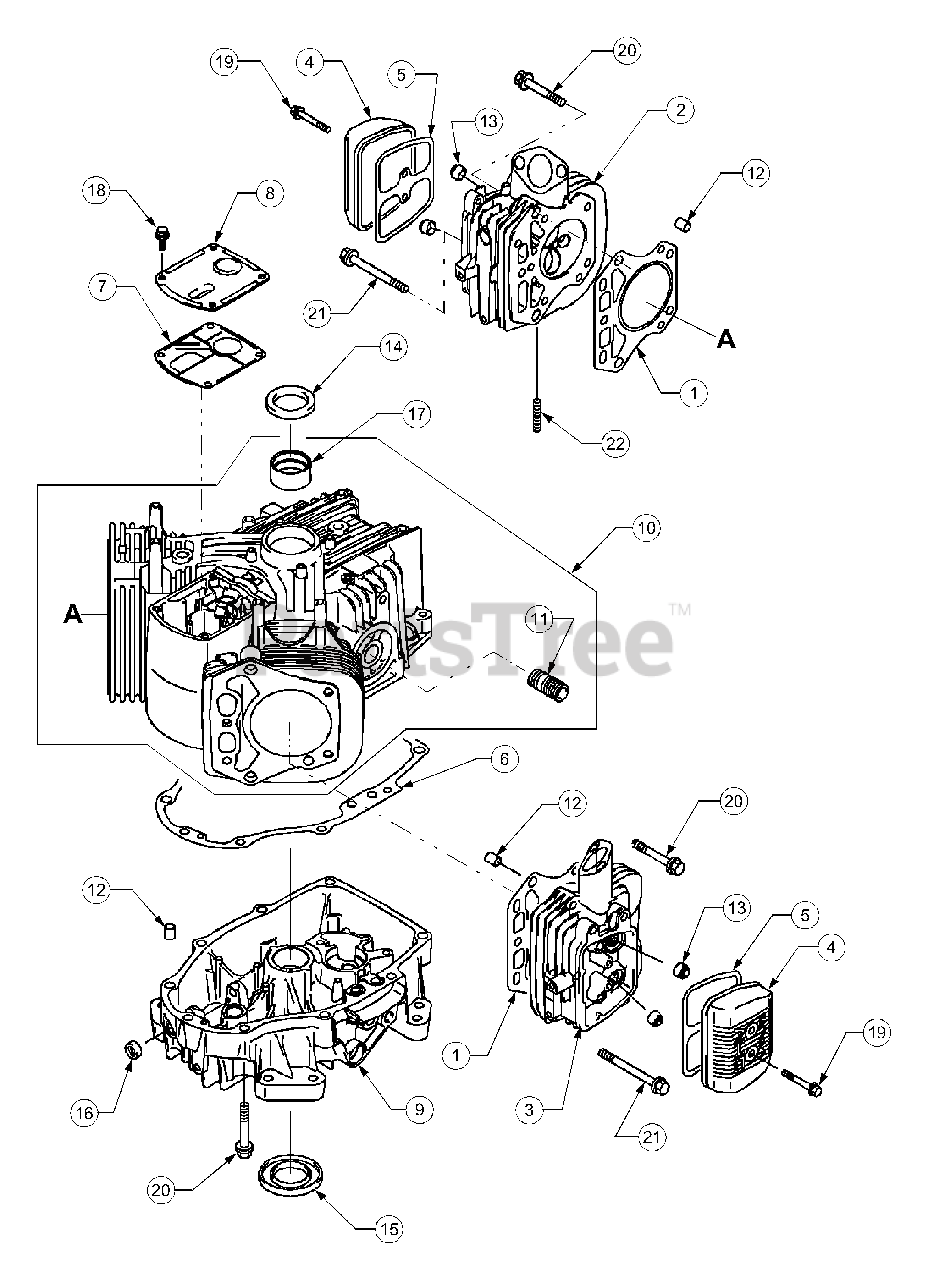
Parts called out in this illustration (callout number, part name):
1	Gasket, Head
2	Head, Cylinder #1 Complete
3	Head, Cylinder #2 Complete
5	Gasket, Rocker Case
6	Gasket, Crankcase Cover
7	Gasket, Breather
9	Cover, Crankcase
10	Crankcase, Complete
13	Seal, Oil rvc2 6x11x10.2
14	Seal, Oil 35-48-8 Tc
15	Seal, Oil 35-62-8 Tc
16	Seal, Oil 8x14x5 Hs
17	Bushing
18	Bolt, Flanged
19	Bolt, Flanged
20	Bolt, Flanged
21	Bolt, Flanged
22	Bolt, Stud
